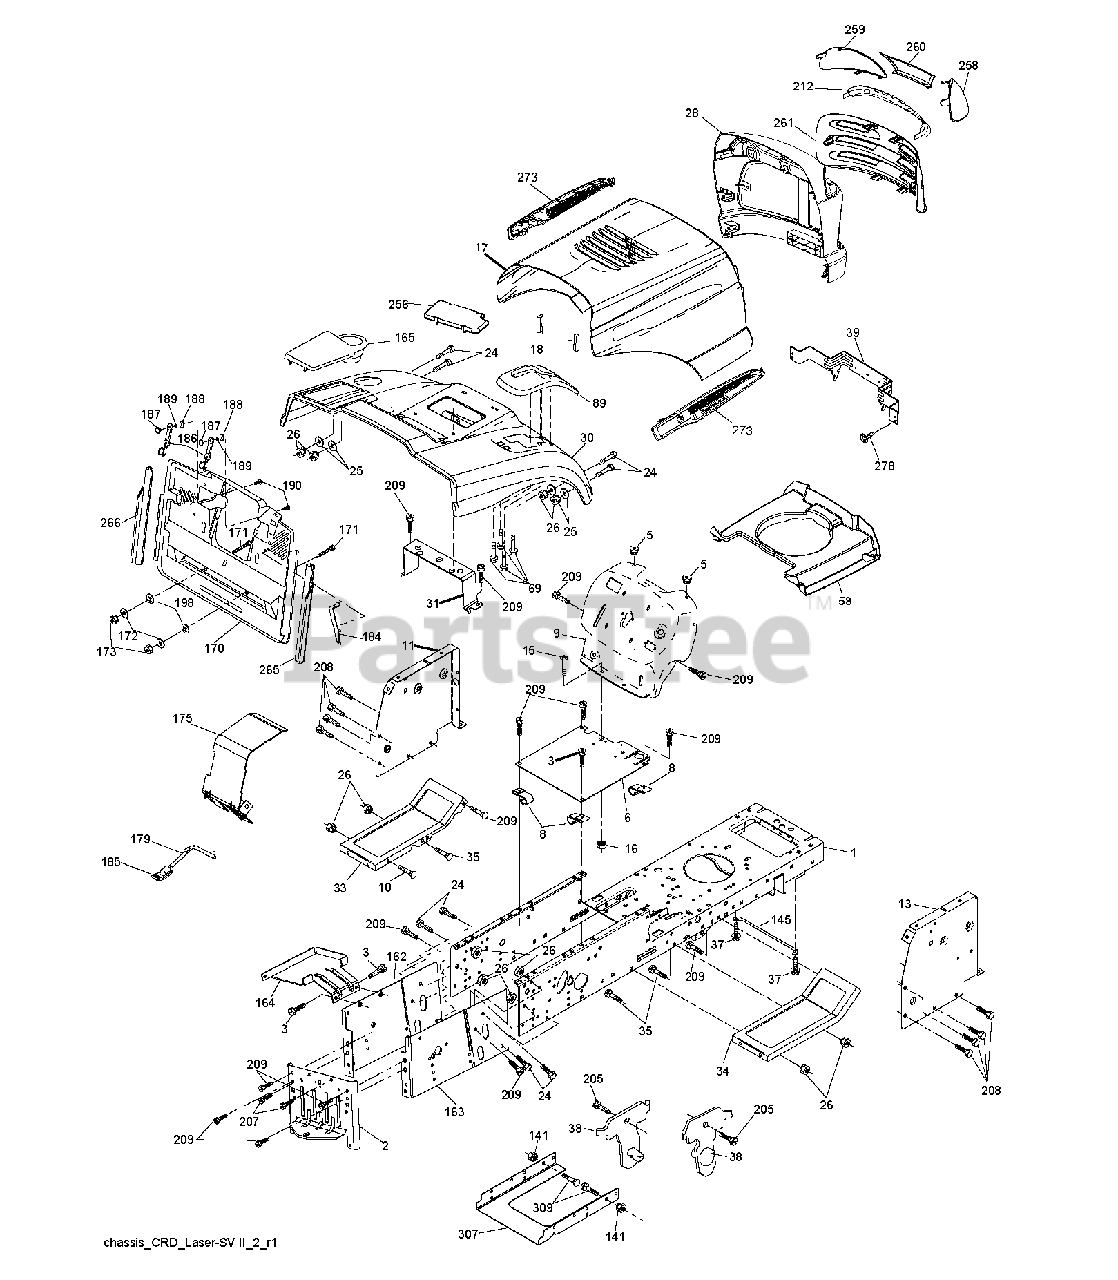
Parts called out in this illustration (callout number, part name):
1	CHASSIS
3	SCREW 3/8-16X3/4
5	BUMPER.RUBBER.HOOD
8	CLIP,INSULATOR
10	BOLT D
11	PANEL.DASH.LH.LTX
13	PANEL ASM, DASH RH
16	NUT
18	BUMPER.HOOD.LARGE.1.75"
25	WASHER
26	NUT
31	BRACKET SUPPORT FENDER
39	BRACKET PIVOT
69	SCREW.HI-LO.CONSOLE
141	NUT LOCK FLG 3/8-16 UNC
145	ROD.PIVOT.HOOD
164	SUPPORT
171	BOLT
172	WASHER
186	LATCH ASSY
187	WELDNUT
189	LOCKWASHER
207	SCREW, 5/16-18 X 1/2
208	SCREW 3/8-16X1/2
209	SCREW, 3/8-16X3/4
278	SCREW.#10 X 0.750.BOS THREAD
